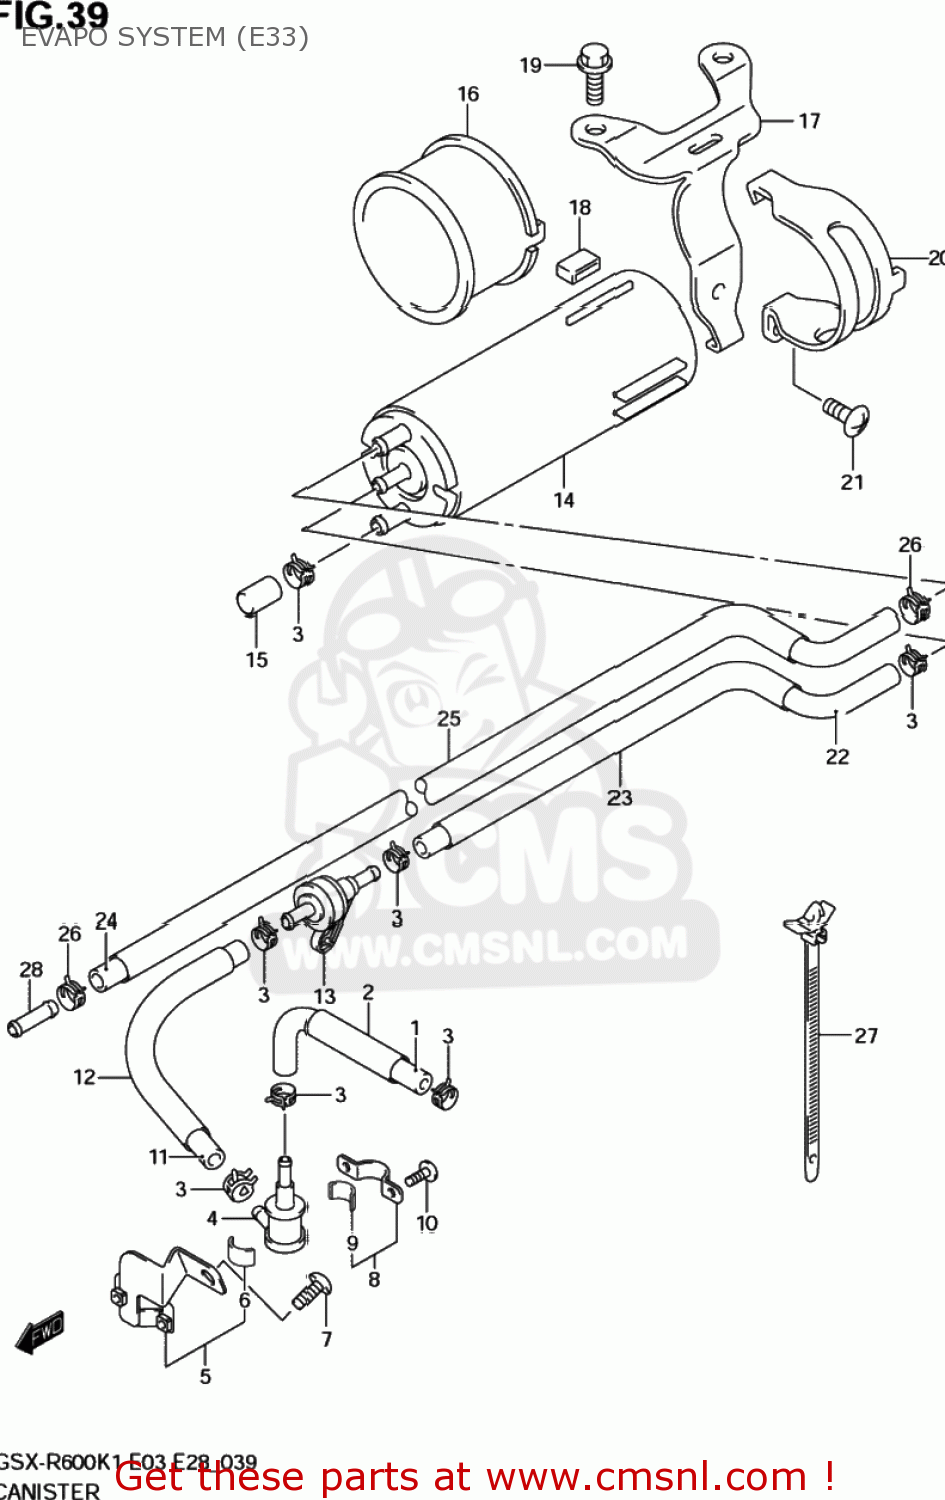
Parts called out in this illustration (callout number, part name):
1	HOSE,TANK & BREATHER VALVE
2	PROTECTOR(14.5X15.5X600)
3	CLIP
4	VALVE,FUEL TANK BREATHER
5	PLATE,TANK BREATHER VALVE
6	CUSHION
7	SCREW 6X10
8	PLATE,FUEL TANK BREATHER NO.2
9	CUSHION
10	SCREW
11	HOSE(5.4X11.4X600)
12	HOSE(5.4X11.4X600)
13	PROTECTOR(14.5X15.5X600)
14	VALVE,2 WAY & BREATHER VALVE
15	CANISTER ASSY,CHARCOAL
16	CAP,OD:11.5
17	CUSHION,CANISTER
18	BRACKET,CANISTER
19	BOLT(6X25)
20	CUSHION
21	WASHER
22	HOLDER,CANISTER
23	SCREW 6X10
24	HOSE(5.4X11.4X600)
25	PROTECTOR(14.5X15.5X600)
26	HOSE(5.4X11.4X760)
27	PROTECTOR(14.5X15.5X600)
28	CLIP
29	CLAMP(L:120)
30	UNION
